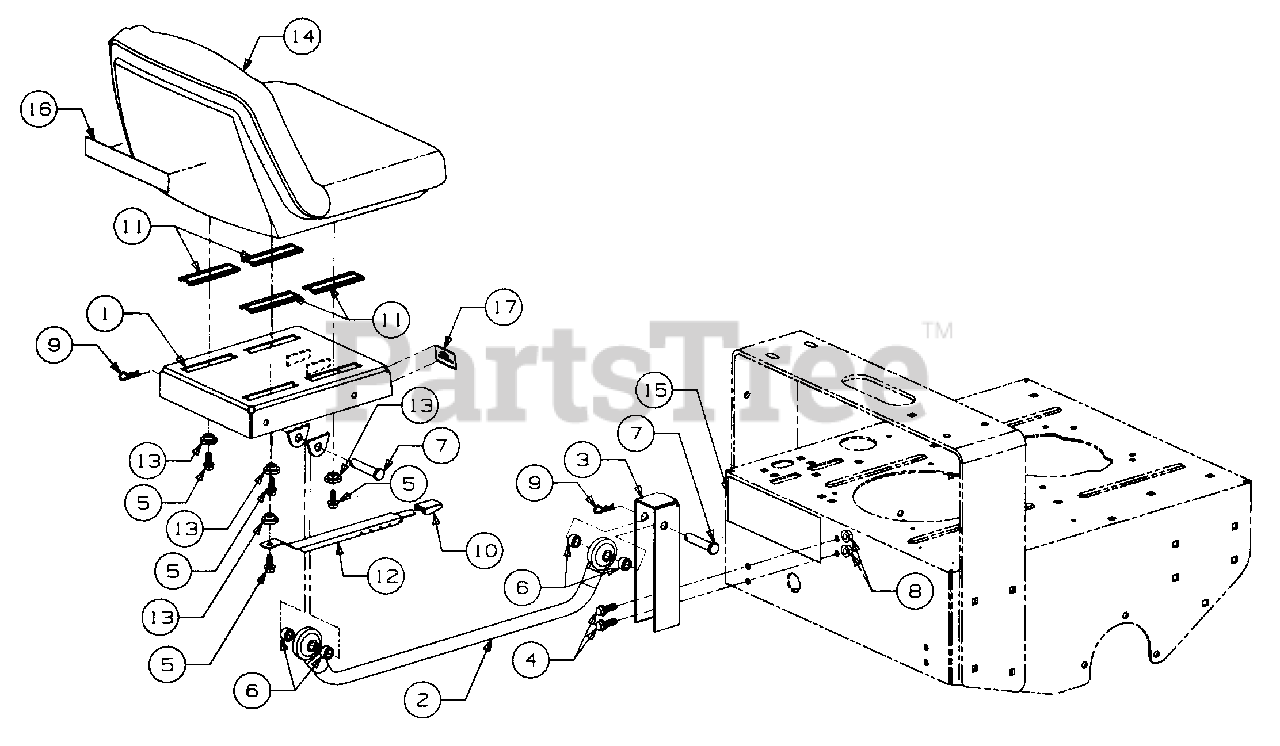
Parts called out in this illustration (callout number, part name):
2	Tube Assy, Link
5	Screw, Hex Wash TPTT, 5/16-18 X .75 Lg
6	Spacer, .53 ID X .75 OD X .38 Lg
7	Pin, Clevis, 1/2 Dia X 2.50 Lg
8	Nut, Hex Flanged Lock, 3/8-16
9	Pin, Internal Cotter
10	Knob, Seat Adjuster
11	Slide, Seat
12	Adjuster, Seat
13	Spacer, Shoulder
14	Seat, Highback
15	Graphic, Warning
16	Graphic, Seat Back Script
17	Graphic, Seat Adjuster
